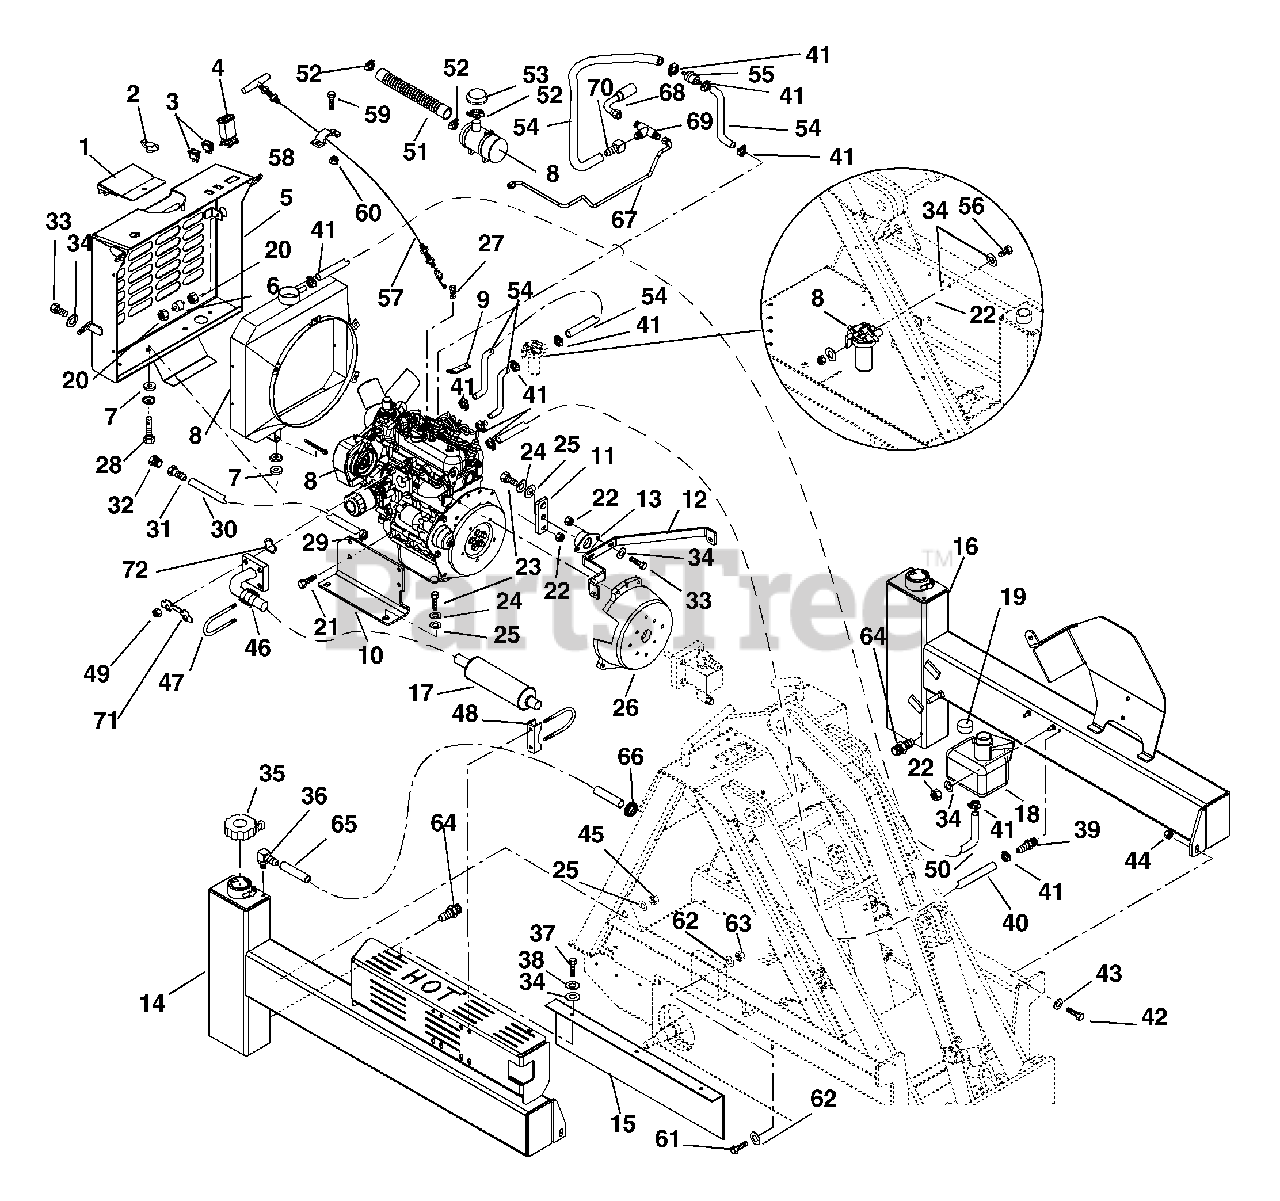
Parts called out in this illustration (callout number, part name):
1	Cover, Radiator Cap
2	Knob, Hand
3	Light Indicator
4	Hour Meter
5	Guard, Radiator
6	Mount, Stud/Plate
7	Isolator
8	Engine, Kubota
8	Filter, Air-Diesel
8	Filter, Fuel-Kubota Diesel
8	Filter, Oil-Kubota Diesel
9	Bracket, Throttle Cable
10	Mount, Engine Right Hand Diesel
10	Mount, Engine Left Hand Diesel
11	Plate, Tie
12	Bracket, Upper Engine
13	Mount, Engine
14	Tank, Fuel Diesel Right Hand
15	Bracket, Muffler
16	Tank, Fuel Diesel Left Hand
18	Tank, Plastic 1.5 Quart
19	Cap, 1.62 Vented
20	Nut-Hex M6 x 1.0
21	Bolt, Hex M10-1.25 x 20
22	Nut-Locking-Nylon M8-1.25
23	Bolt-Hex .50-20X1.00 Grade 5
24	Washer-Locking .50 x .125
25	Washer-Flat-Steel .531 x 1.06 x .095
26	Housing, Bell Kubota Assembly
27	Swivel Assembly
28	Bolt,Hex M10-1.25X40 with Lock Hole
29	Clamp-Hose Worm .44/.78 x .53
30	Hose, Oil Drain
31	Adapter, Female Swivel .75-16F
32	Plug, Hose Swivel .75-16M
33	Bolt-Hex M8-1.25 x 20
34	Washer-Flat-Steel .344 x .688 x .065
35	Cap, Fuel Tank
36	Fitting, Barbed 90 Degree Elbow .125-27M x .25 I.D. Hose
37	Bolt-Hex M8 X 1.25 x 16
38	Washer-Locking .31 x .078
39	Fitting, Barbed .125-27M x .250 I.D. Hose
40	Gas Line-Bulk 1/4" I.D.
41	Hose Clamp
42	Bolt M10 x 1.5 x 40
43	Washer-Flat-Steel .406 x .812 x .065
44	Nut-Locking-Nylon M10-1.5
45	Nut-Locking-Nylon M12-1.75
46	Pipe, Exhaust
47	Clamp, Muffler U-Bolt
48	Clamp, Muffler 3.50
49	Nut-Hex M8-1.25
50	Hose,5/16 I.D.
51	Hose, Flexible
52	Clamp, 2.25 Diameter Hose
53	Filter, Pre Diesel
54	Hose, .312 I.D.
55	Filter, Fuel .312 I.D. Hose
56	Bolt-Hex M8-1.25 x 65
57	Cable, Throttle-Diesel
58	Clamp, Cable
59	Bolt-Hex M5 .8 x 16
60	Nut-Locking-Nylon M5 .8
61	Bolt-Hex M6-1.0X25
62	Washer-Flat-Steel .281 x .62 x .065
63	Nut-Locking-Nylon M6-1
64	Adapter, Male Connector .562-19M x .125-27M
65	Gas Line-Bulk .25 I.D.
67	Tube-Fuel Line Long
68	Tube-Fuel Line Short
69	Adapter-Tee .56-18
70	Fitting-Hose .375-M6
71	Bracket, Lock
72	Washer, Wave
